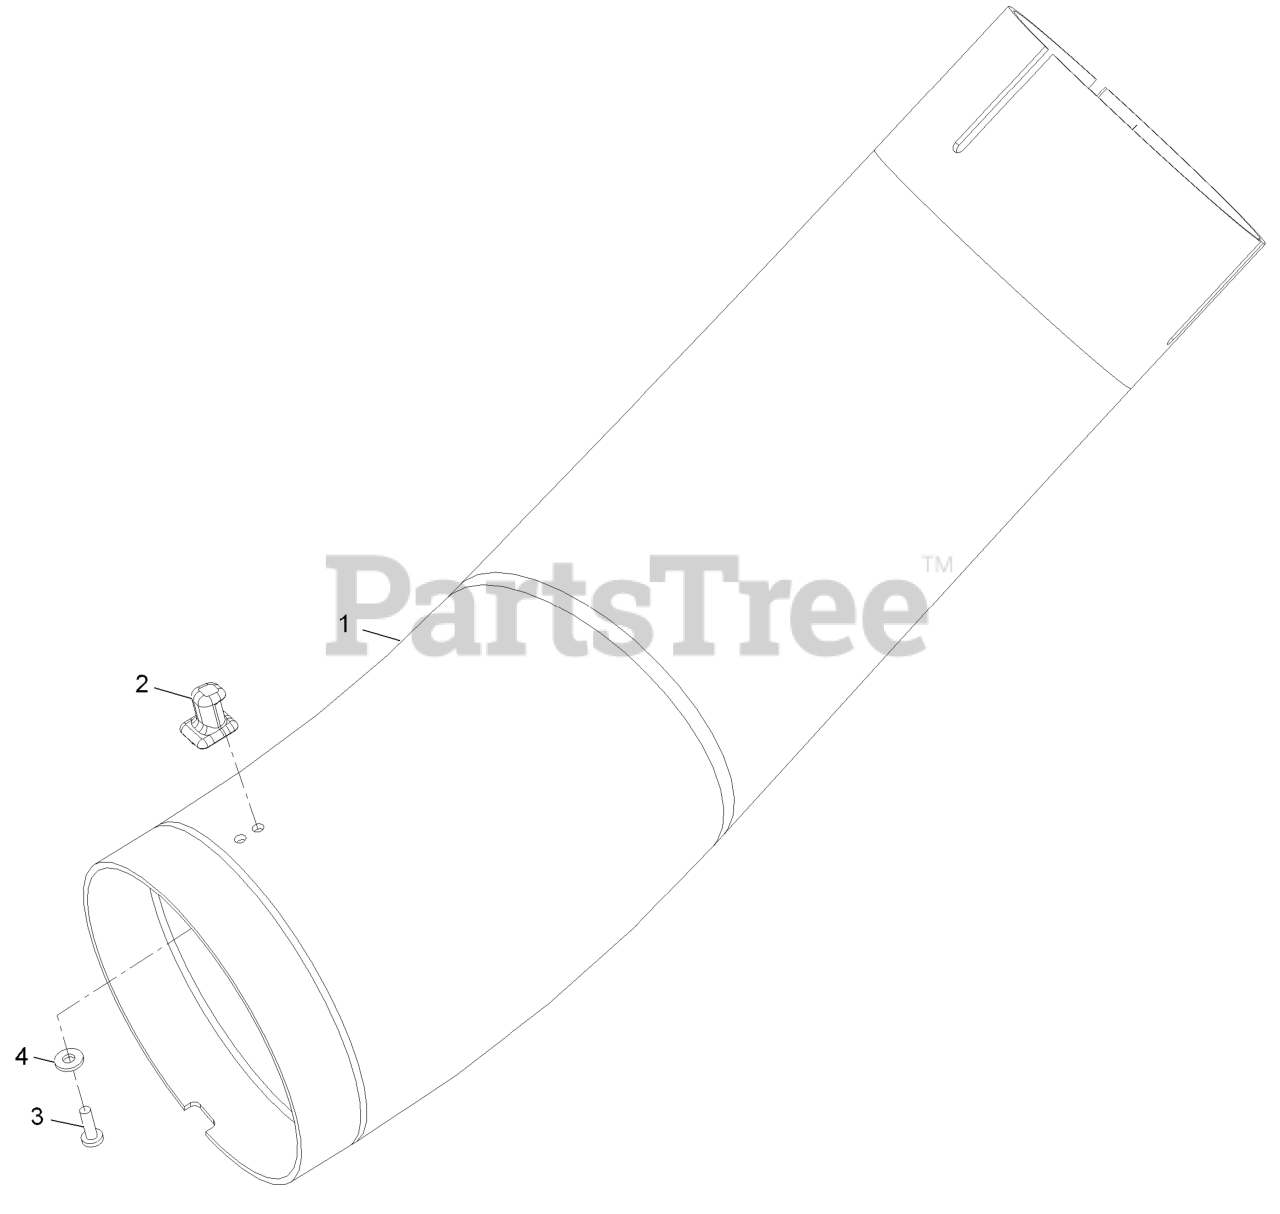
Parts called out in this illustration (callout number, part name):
1	Tube-Lower, Short
2	LATCH-KEEPER
3	SCREW-PPH
4	WASHER-FLAT
